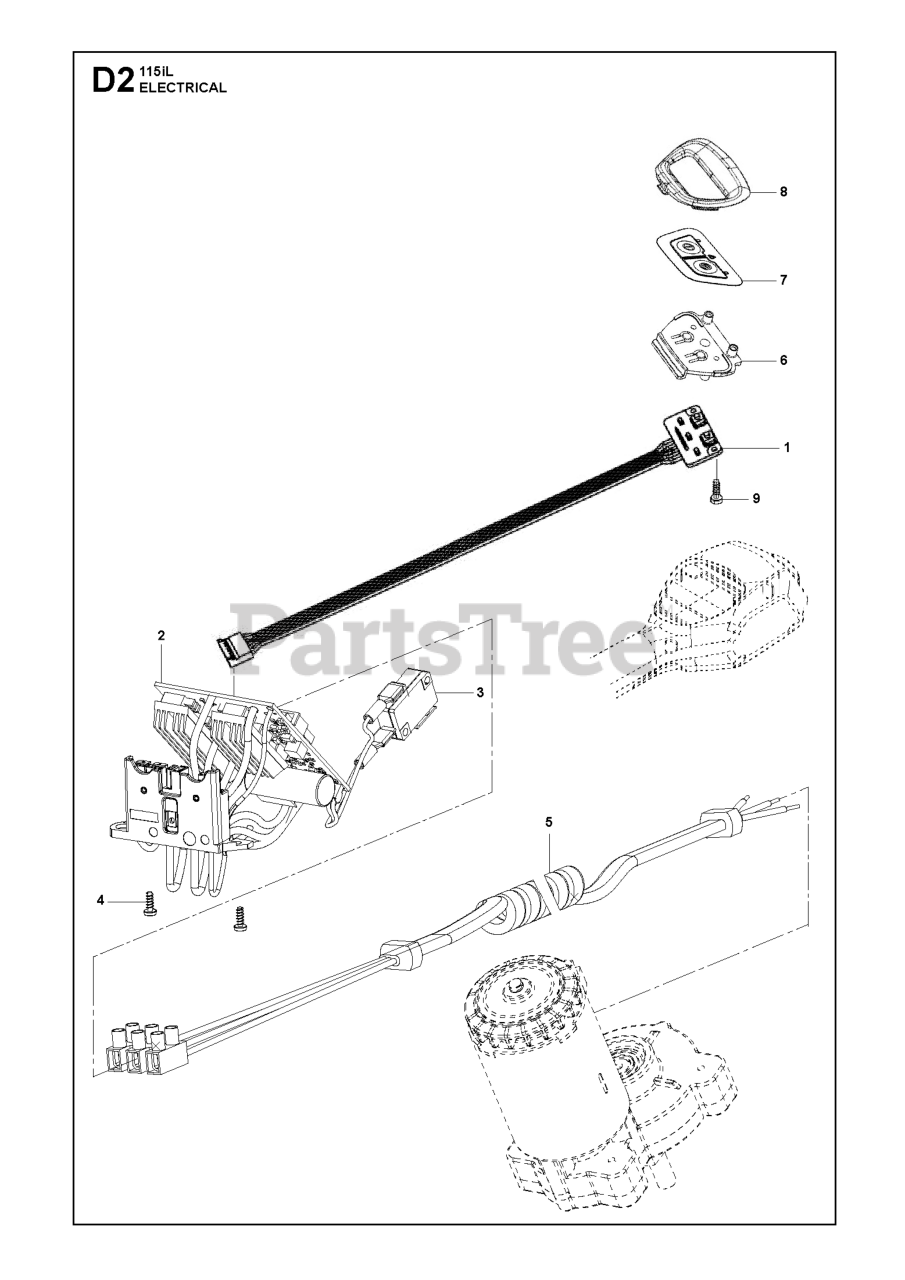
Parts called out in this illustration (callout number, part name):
1	KEYPAD
2	CONTROL UNIT
4	SCREW ST3X8
6	BRACKET
7	KEYPAD GRAPHICS
8	PANEL KEYPAD
9	SCREW ST3X8
